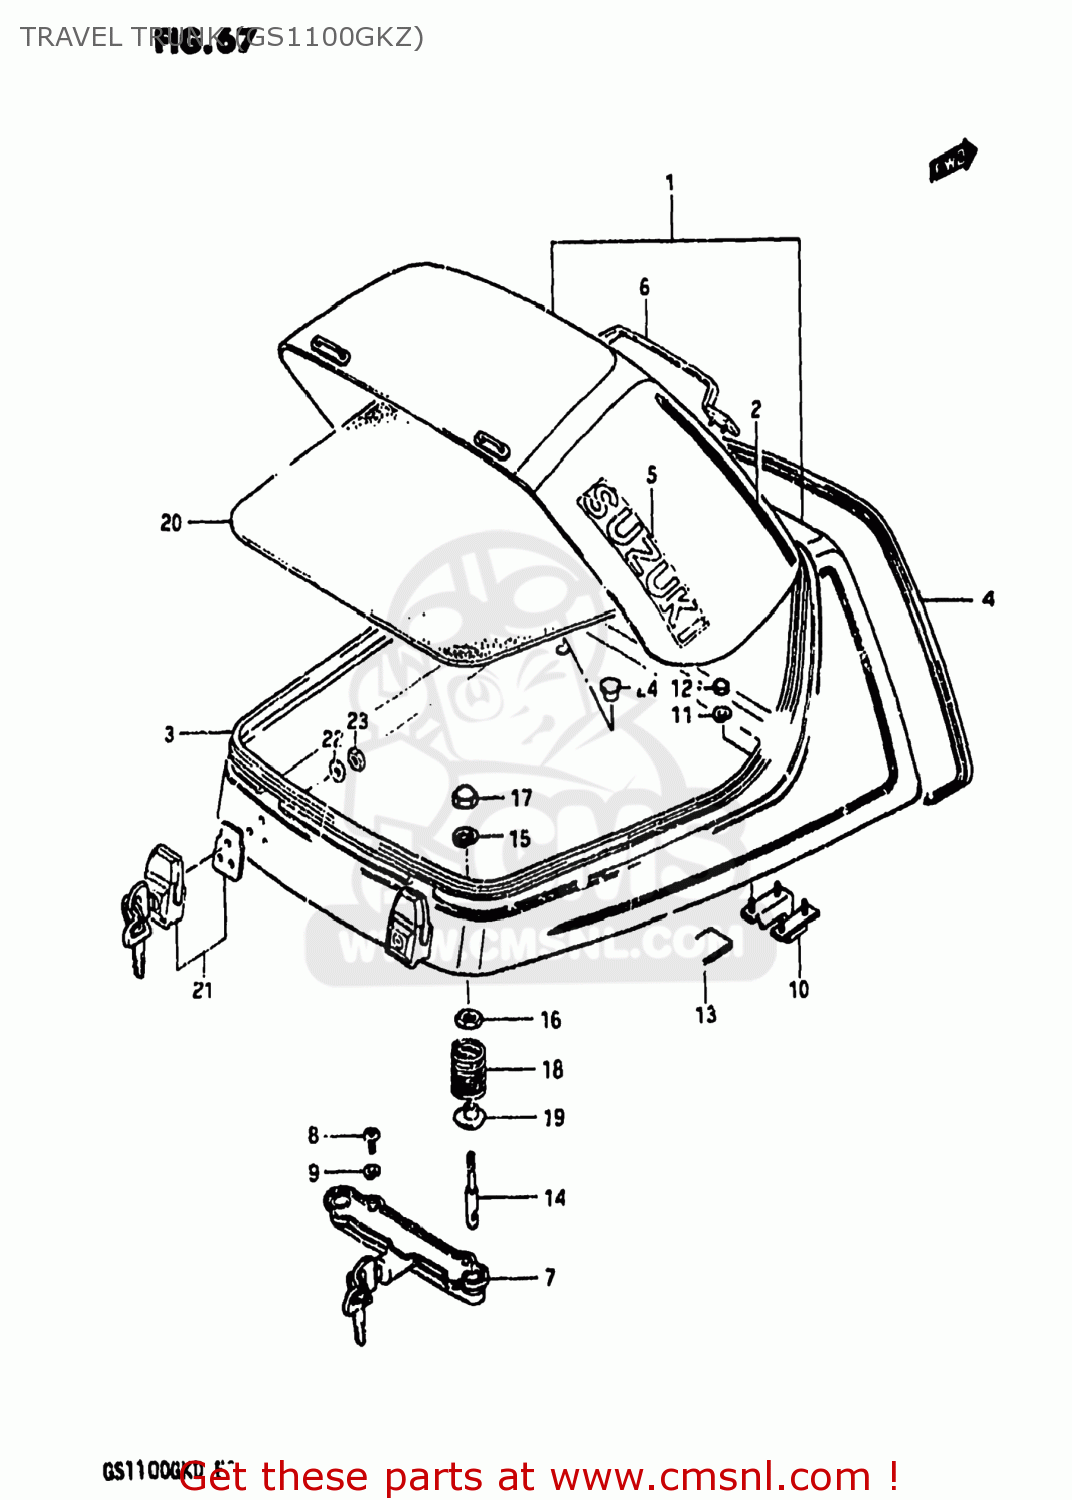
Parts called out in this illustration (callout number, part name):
1	TRAVEL TRUNK (BLACK)
2	TAPE SET,COWLING BODY
3	SEAL,TRAVEL TRUNK
4	MOLDING,TRAVEL TRUNK
5	EMBLEM
6	GRIP TRAVEL TRUNK
7	LOCK,TRAVEL TRANK
8	SCREW 6X12
9	LOCK WASHER
10	HOOK COMP TRAV TRUNK
11	LOCK WASHER
12	NUT
13	CUSHION TRAVEL TRUNK
14	LOCK BOSS TRAV TRUNK
15	WASHER,LOCK,8.
16	NUT 8MM
17	NUT
18	SPRING,TRAVEL TRUNK
19	GUIDE,TRAVEL TRUNK SPRING
20	CUSHION TRAVEL TRUNK
21	LOCK,TRANK LID
22	WASHER
23	NUT 4MM
24	PLUG(OD:14)
